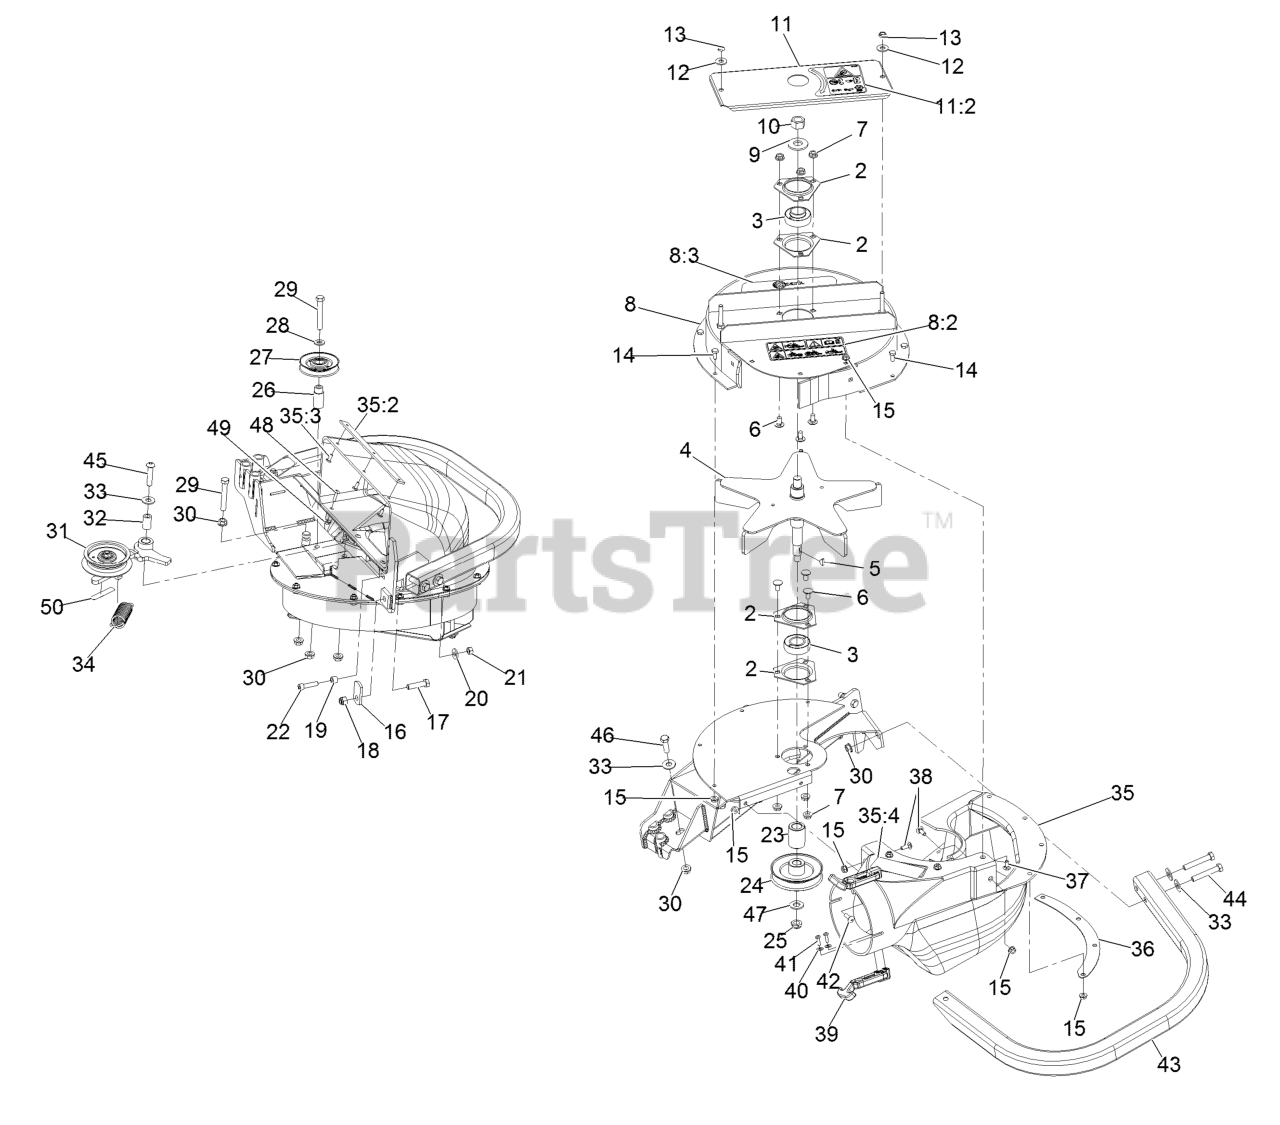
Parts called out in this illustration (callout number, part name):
2	Housing-Flange
3	Bearing
4	Impeller
5	Key-Woodruff 3/16 X 5/8
6	Bolt-Carriage 5/16-18 X 5/8
7	Nut-Whizlock 5/16-18
8	Upper-Housing W/Decal
8:2	Decal-Ultravac S-Series
8:3	Decal-Warning
9	Washer-Spring Disc 5/8
10	Nut-Hex 5/8-18
11	Cover-Bearing W/Decal
11:2	Decal-Warning
12	Washer-5/16 Std
13	Nut-Nyloc 5/16-18 Thin
14	Screw-HH 1/4-20 X 5/8
15	Nut-Whizlock 1/4-20
16	Latch-Catcher, Grass
17	Screw-HH 3/8-16 X 1 1/2
18	Nut-Nyloc 3/8-16
19	Bushing
20	Washer-Spring Disc 5/16
21	Nut-Hex 5/16-18
22	Screw-Sh 5/16-18 X 1 1/4
24	Sheave-Blower
25	Nut-Lock, NI
27	Idler-Inside
28	Washer-3/8 SAE
29	Screw-HH 3/8-16 X 2 1/2
30	Nut-Whizlock 3/8-16
31	ASM, Idler
32	Bushing-Pivot, Idler
33	Washer-3/8 Std
35	Chute, Blower (46, 50 And 56)
35:2	Plate-Reinforcing
35:4	Decal-Warning
36	Plate-Backing, Blower
37	Bolt-Carriage 1/4-20 X 5/8
38	Bolt-Carriage 1/4-20 X 3/4
39	Latch-Rubber
40	Washer-#10 Std
41	Screw-PPH #10-24 X 5/8
42	Screw-PPH 1/4-20 X 3/4
44	Screw-HH 3/8-16 X 2 1/4
45	Screw-Button Head 3/8-16 X 1 3/4
46	Screw-HH 3/8-16 X 1 1/4
47	Washer-1/2 SAE
48	Screw-Truss Head #10-24 X 3/4
49	Nut-Whizlock #10-24
50	Decal-Warning
